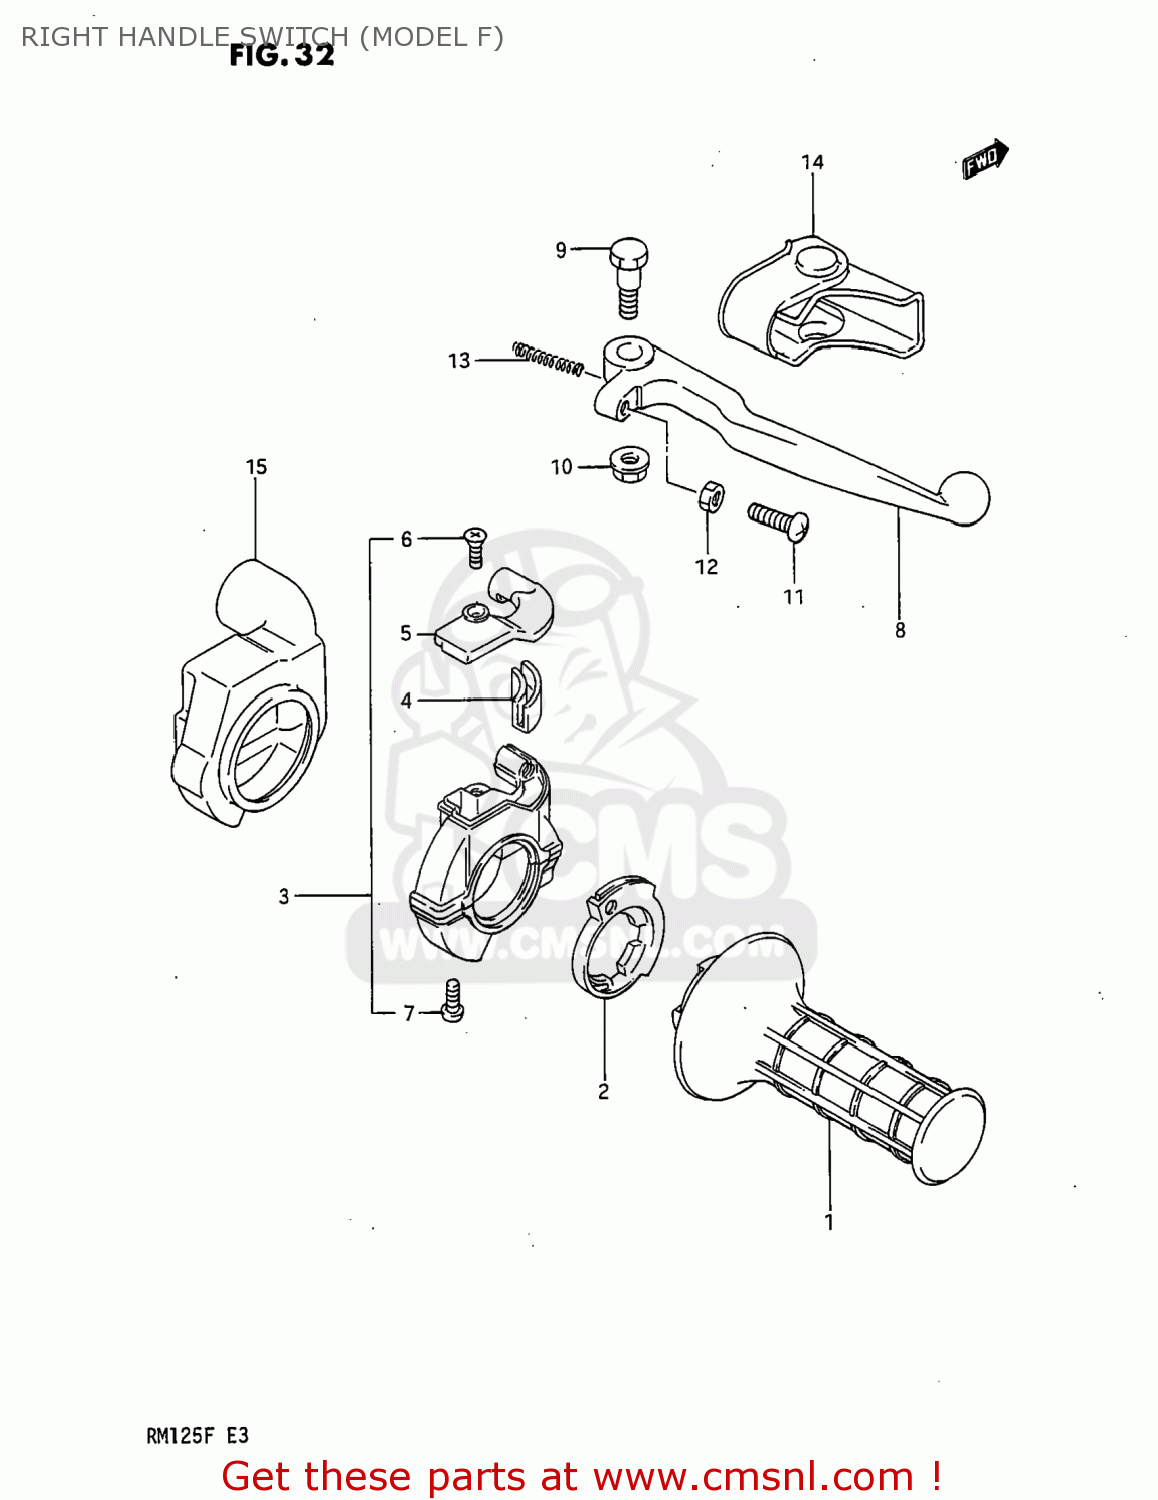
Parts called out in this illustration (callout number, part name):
1	GRIP,THROTTLE
2	ROTOR,THROTTLE GRIP
3	CASE ASSY,THROTTLE
4	GUIDE PIECE,THROTTLE
5	COVER,THROTTLE CASE
6	SCREW
7	SCREW
8	LEVER,BRAKE
9	BOLT,BRAKE LEVER
10	NUT,BRAKE LEVER
11	BOLT,LEVER
12	NUT ,5MM
13	SPRING,RETURN
14	COVER,BRAKE LEVER
15	COVER,THROTTLE CASE
